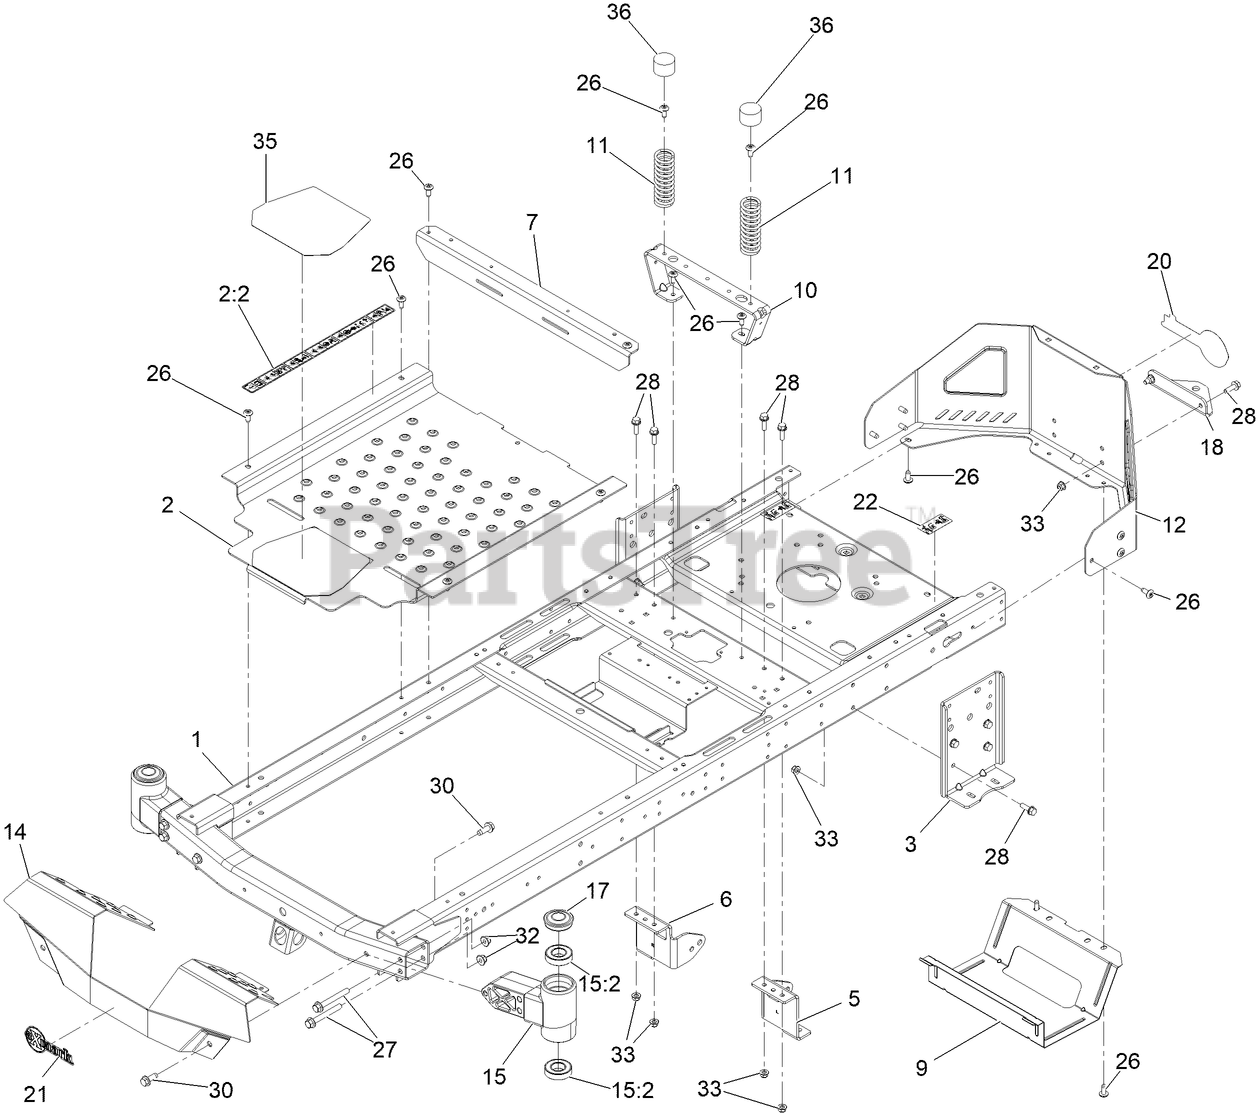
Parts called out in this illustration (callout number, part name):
1	FRAME ASM - RIVETED/WELDED
2	Pan-Floor ASM
2:2	DECAL-WARNING
3	PLATE-MOUNT, HYDRO
5	MOUNT-HYDRO, FRONT (RIGHT
6	Mount-Hydro, Front (Left)
7	BRACE-CROSS
9	GUARD-MUFFLER
10	SUPPORT-SEAT
11	SPRING-COMPRESSION
12	GUARD-ENGINE
15	AXLE-STUB
15:2	BEARING-BALL
17	Cap-Grease
18	BRACKET-HITCH
20	DECAL-EXMARK LOGO
21	DECAL-EXMARK LOGO
22	DECAL-BYPASS
27	SCREW-HHF
28	SCREW-HHF
30	SCREW-HWH
32	NUT-HF, NI
33	NUT-HF, NI
35	TREAD-STEP
36	CAP-PROTECTOR
